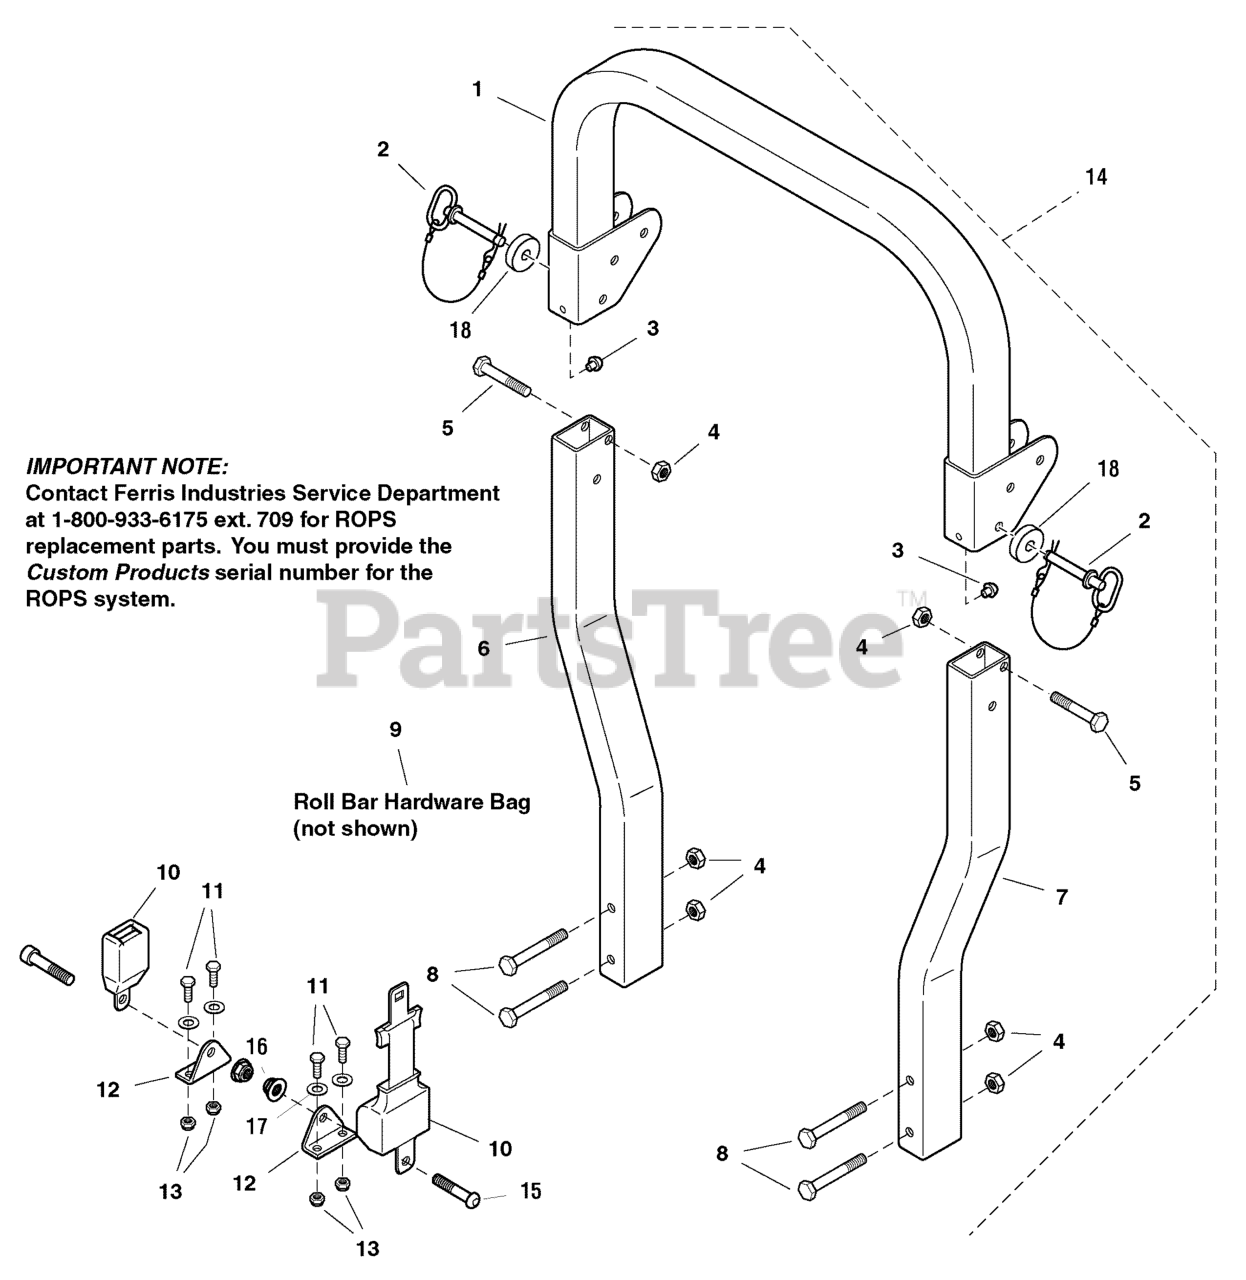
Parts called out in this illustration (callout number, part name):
1	ROLL BAR TOP LOOP
2	PIN, HITCH, BLACK W/ PLASTIC LANYARD
3	RUBBER BUMPER
4	NUT
5	BOLT
6	ROLL BAR POST, RH
7	ROLL BAR POST, LH
8	BOLT
9	ROLL BAR HARDWARE BAG
10	SEAT BELT, RETRACTING - ASSM
10	SEAT BELT ASSEMBLY, EXTRA LONG
11	BOLT, 3/8-16 X 1" GD5 CZ
12	PLATE, SEAT BELT, BRACKET - RED
13	NUT, 3/8-16 HEX NYLOCK FLANGE
14	ROPS (Call 1-800-933-6175 ext. 2193 if replacing a ROPS)
15	SCREW, 1/2-13 X 1.00, SHCS
16	NUT, Hex Flange, Nylock, 1/2-13
17	WASHER, 3/8 SAE
18	RUBBER WASHER
